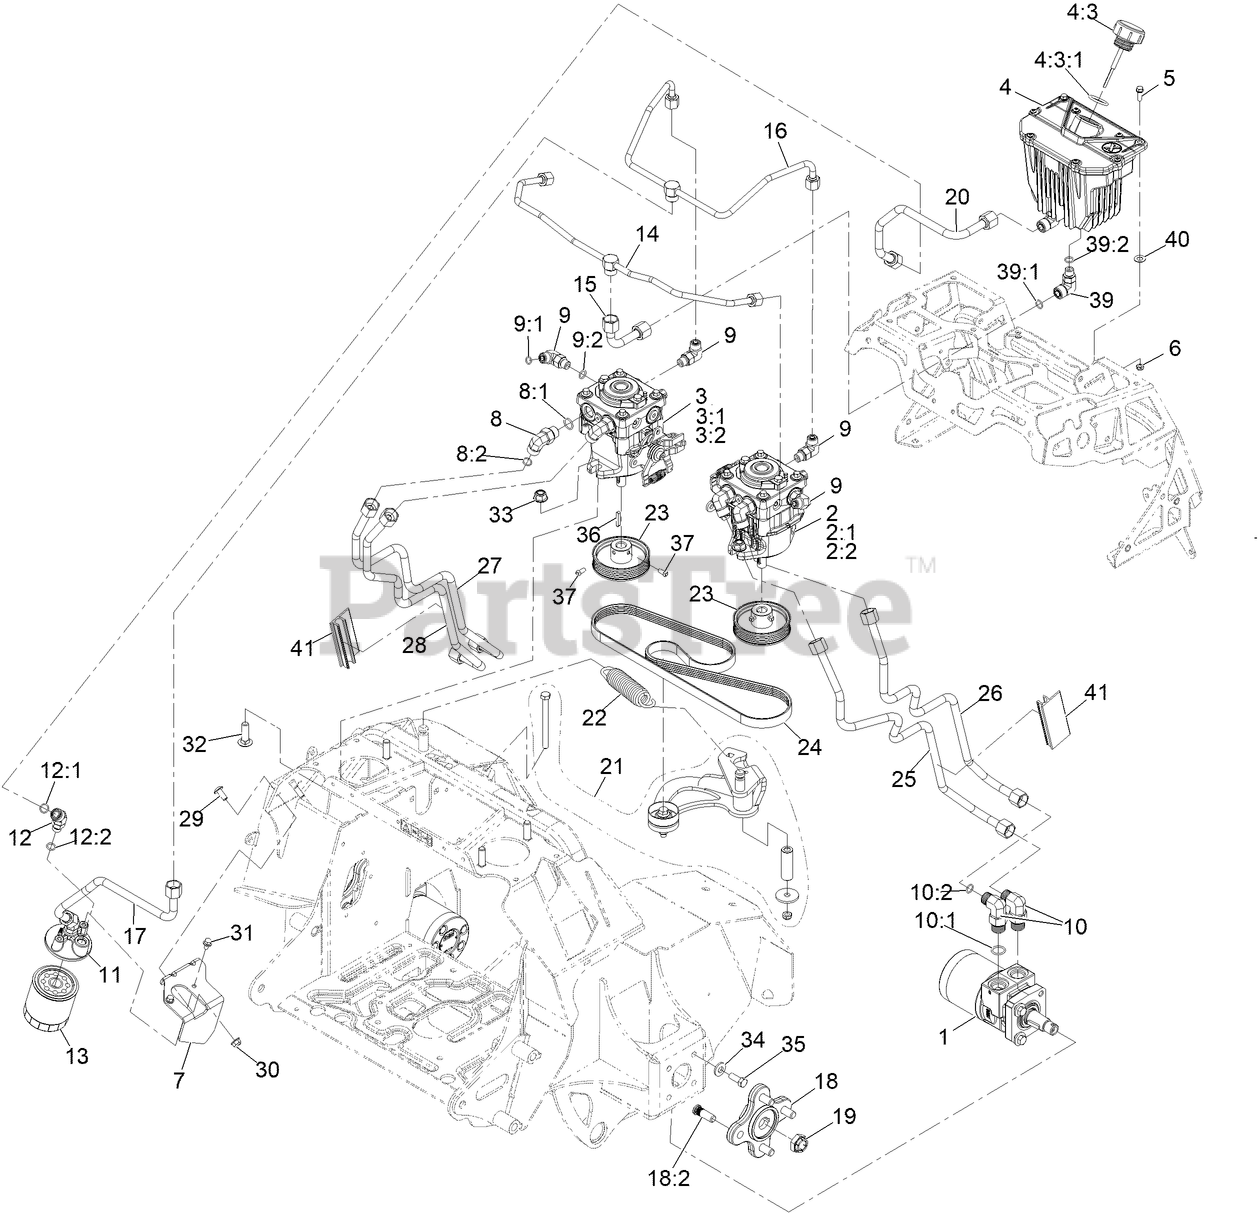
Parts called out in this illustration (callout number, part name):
1	MOTOR-WHEEL
2	PUMP-HYDRAULIC 10CC
2:1	KIT, 10CC/12CC PUMP KIT
2:2	SEAL OVERHAUL KIT
3	PUMP-HYDRAULIC 10CC
3:1	KIT, 10CC/12CC PUMP KIT
3:2	SEAL OVERHAUL KIT
4	ASM, HYDRAULIC RESERVOIR
4:3	Cap, Hydraulic
5	SCREW-HWH
6	NUT-LOCK, NI
7	MOUNT, FILTER
8	FITTING-ELBOW, 90 DEG
8:1	O-RING
8:2	O-RING
9	FITTING-ELBOW, 90 DEG
9:1	O-RING
9:2	O-RING
10	FITTING-ELBOW, 90 DEG
10:1	O-RING
10:2	O-RING
11	HEAD-FILTER
12	Adapter
12:1	O-RING
12:2	O-RING
13	FILTER-25 MICRON, BI-DIRECTIONAL
14	LINE, HYDRAULIC, CASE TEE
15	LINE, HYDRAULIC, CASE
16	LINE, HYDRAULIC, CHARGE TEE
17	LINE, HYD. CHARGE
18	ASM-HUB AND STUDS
18:2	STUD-WHEEL
19	NUT-LOCK
20	LINE, HYD. SUPPLY
21	ASM, IDLER ARM
22	SPRING, EXTENSION
24	BELT, PVK5
25	KIT-STE HYD LINE LT REAR B-A
26	KIT-STE HYD LINE LT FRNT A-B
27	KIT-STE HYD LINE RT REAR B-B
28	KIT-STE HYD LINE RT FRNT A-A
29	SCREW-TORX
30	NUT-HF, NI
31	SCREW-HHF
32	BOLT-CARR
33	NUT-HF, NI
34	WASHER-BELLEVILLE
35	SCREW-HH
36	KEY, 5MM X 5MM X 29MM
37	Screw-SQH
39	Fitting-HYD, 90 DEG
39:1	O-RING
39:2	O-RING
40	Washer-Thrust
41	SPACER-HYDRAULIC TUBE
